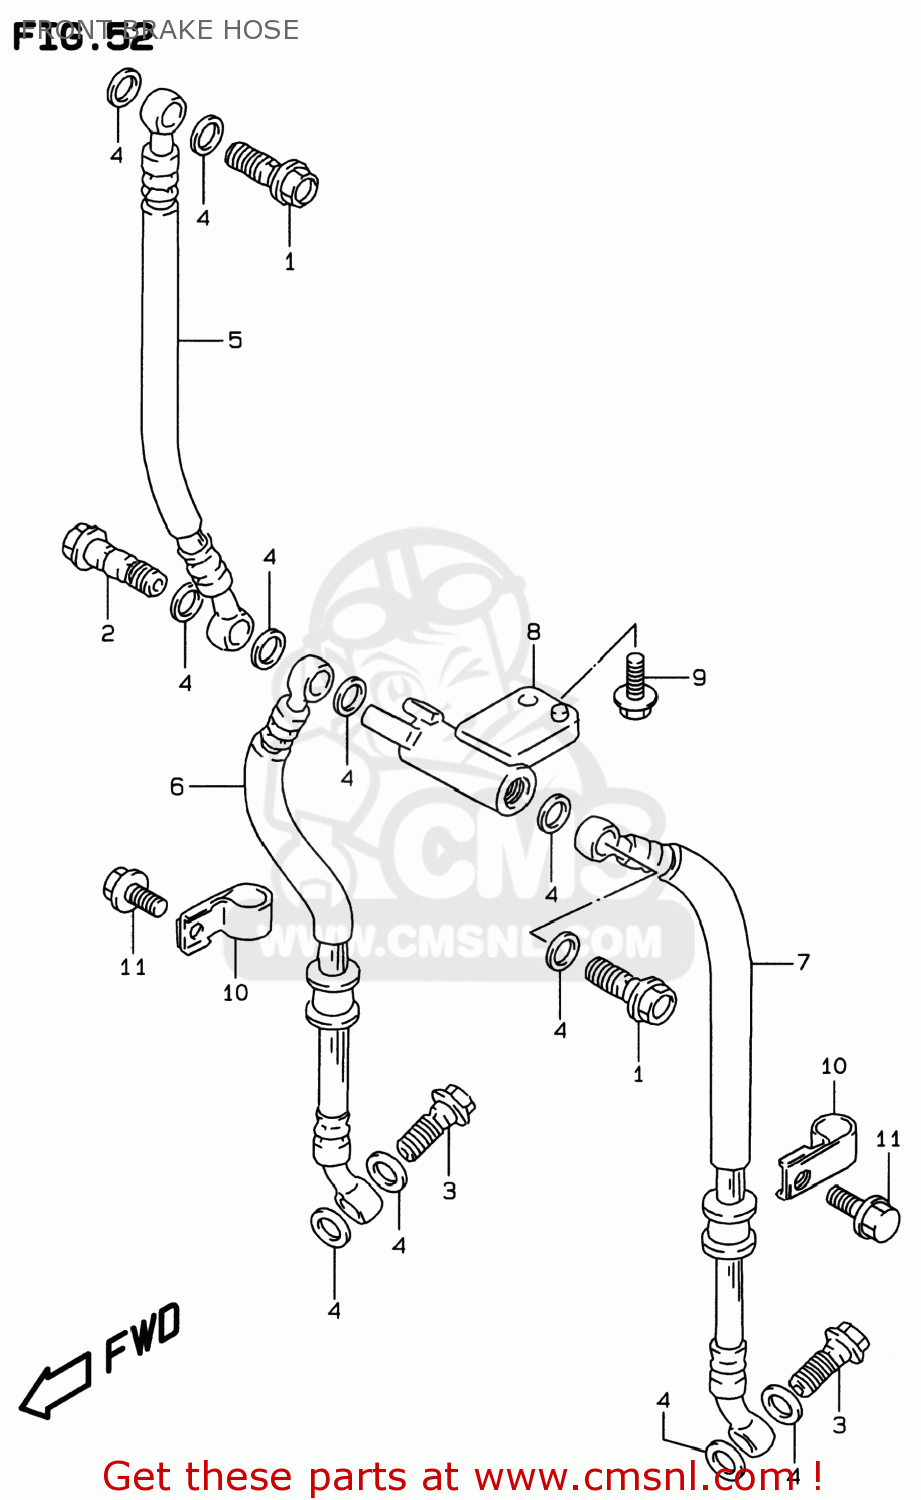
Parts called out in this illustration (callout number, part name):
1	BOLT UNION
2	BOLT UNION
3	BOLT UNION
4	WASHER(10X15X1.5)
5	HOSE COMP,FRONT BRAKE
6	HOSE,FR BRAKE NO.2,R
7	HOSE,FR BRAKE NO.2,L
8	JOINT,BRAKE HOSE
9	BOLT
10	CLAMP,FR BRAKE HOSE NO.2
11	BOLT
